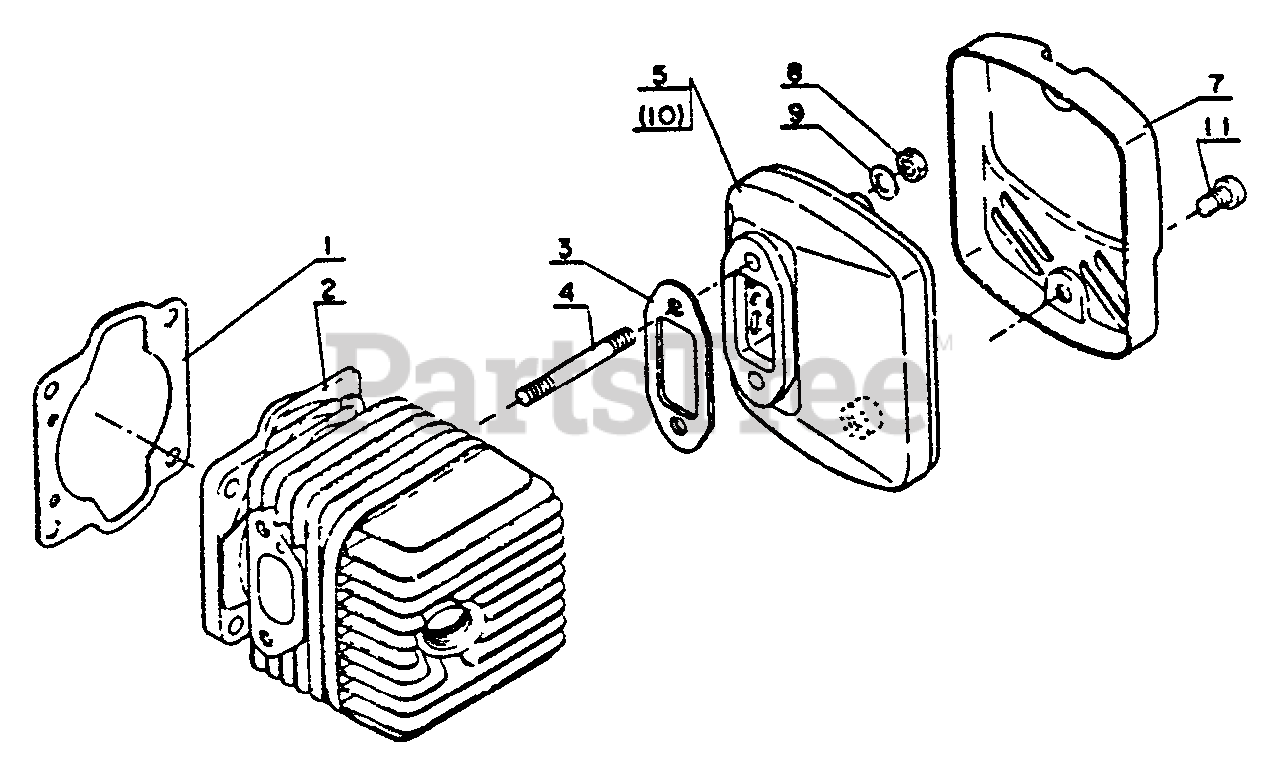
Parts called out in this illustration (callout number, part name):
1	GASKET, CYLINDER
2	CYLINDER
3	GASKET, EXHAUST
4	BOLT, STUD
5	MUFFLER ASSY
7	LID, MUFFLER
8	LOCKNUT - 5
9	WASHER, FLAT 5.5×10×0.8
11	SCREW 5×8
12	BOLT - 5×8
13	WASHER, LOCK 5 MM
